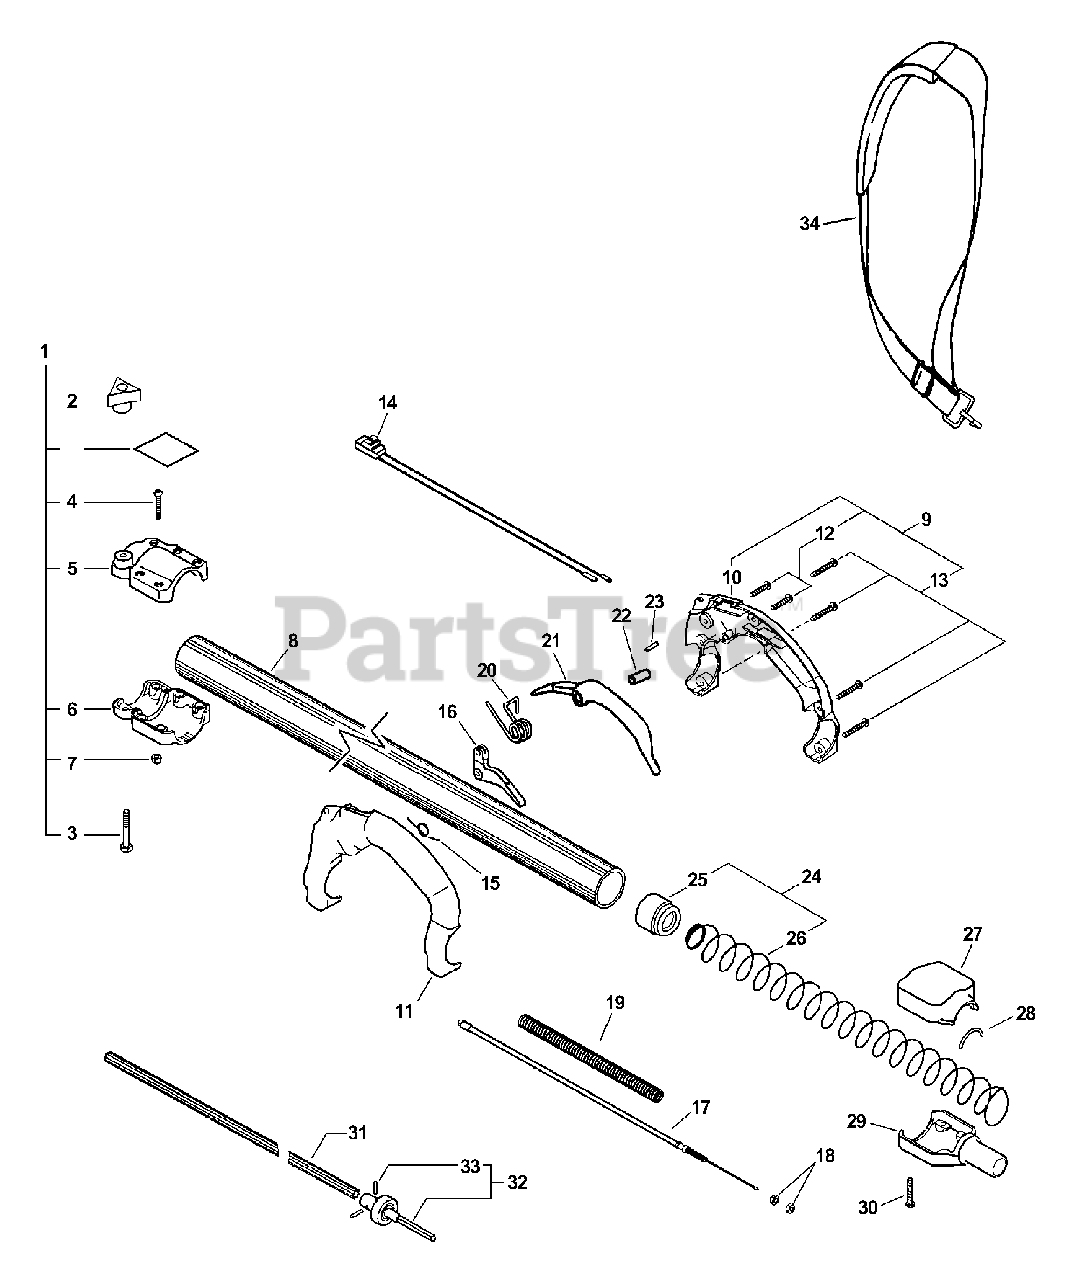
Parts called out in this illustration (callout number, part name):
1	COLLAR ASSY
2	THUMBSCREW
3	SCREW - 1/4-20 X 1-3/4"
4	SCREW - 10-24 X 1-1/4"
5	COLLAR, MAIN PIPE - UPPER
6	COLLAR, MAIN PIPE - LOWER
7	LOCKNUT - 10-24
8	PIPE, MAIN - ORANGE
9	HANDLE ASSY - REAR
10	HANDLE, REAR - RIGHT
11	HANDLE, REAR - LEFT
12	SCREW - 10-24 X 7/8"
13	SCREW - 10-24 X 1-1/4"
14	IGNITION SWITCH ASSY
15	SPRING, TRIGGER
16	TRIGGER, THROTTLE
17	CABLE, THROTTLE
19	TUBE, PROTECTIVE - CORRUGATED
20	SPRING, LOCKOUT LEVER
21	LOCKOUT, THROTTLE
22	COLLAR - 5
23	PIN - LOCATING
24	FLOATING BUSHING ASSY
25	BUSHING, FLOATING
27	LOWER HSNG ADAPT (TOP)
29	ADAPTER - LOWER
30	SCREW - 10-24 X 1-1/4"
31	DRIVESHAFT
32	SHAFT CONNECTOR KIT
34	SHOULDER STRAP ASSY
